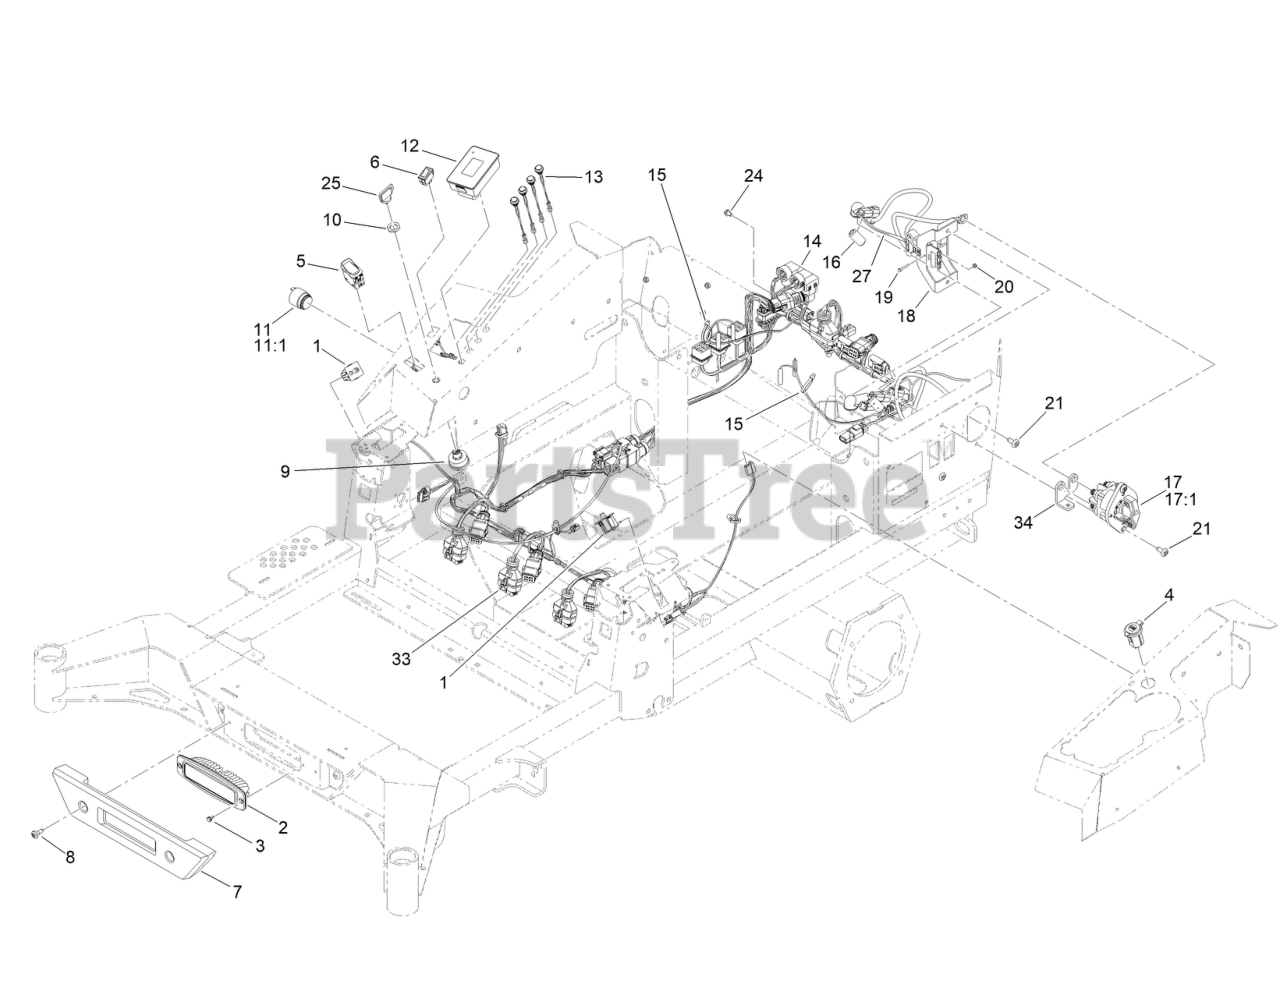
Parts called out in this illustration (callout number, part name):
1	SWITCH-PLUNGER, ON-(ON)
2	MOUNT-FLUSH, LIGHT
3	SCREW-HWH
4	PORT-POWER, USB
5	SWITCH-ROCKER, ON-NONE-ON
6	SWITCH-ROCKER
7	BUMPER-FRONT
8	SCREW-SHOULDER
9	SWITCH-KEY, SPST
11	AUDIO ALARM ASM
11:1	NUT-PLASTIC, KNURLED
12	TDM 2002
13	SWITCH-PUSHBUTTON
14	HARNESS-WIRE, MAIN
15	TIE-CABLE
16	FERRITE, SNAP-ON
17	SWITCH-DISCONNECT
17:1	NUT-HF
18	BRACKET-CHARGER, DUAL
19	SCREW
20	NUT-HEX
24	SCREW-HWH
25	KEY-IGNITION
27	HARNESS-WIRE, CHARGER PORT
33	HARNESS-WIRE, DECK
34	BUSBAR-2, SWITCH
